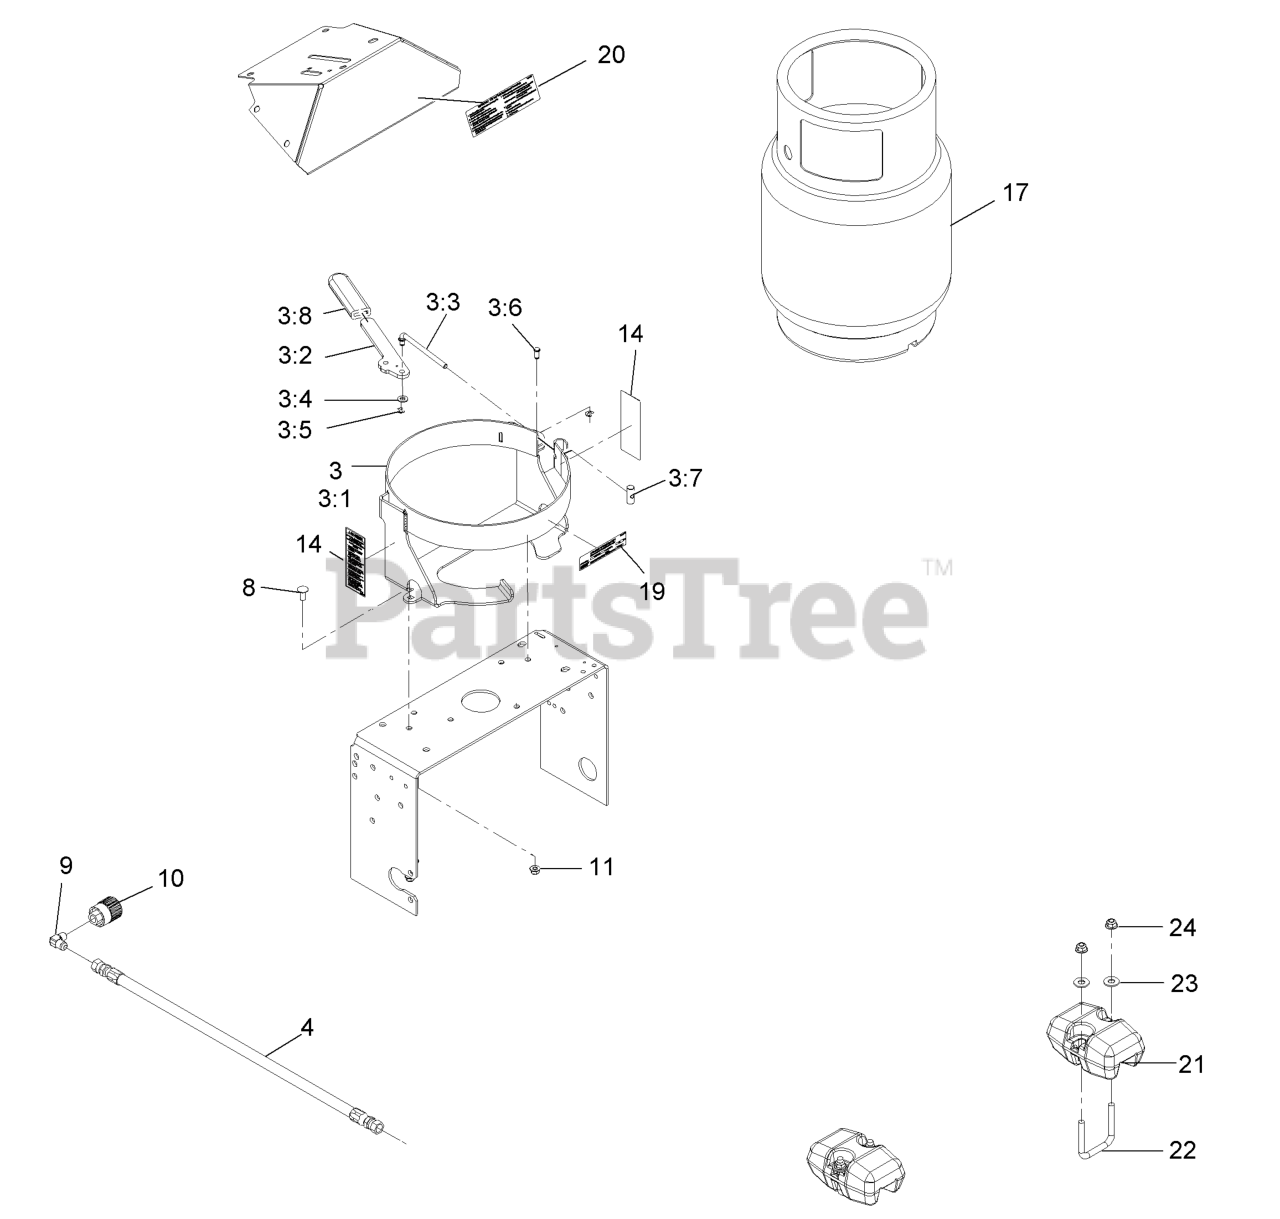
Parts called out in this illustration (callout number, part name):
3	ASM, LP TANK MOUNT
3:1	WELD, TANK MOUNT
3:2	ARM, LEVER
3:3	LINKAGE, LATCH
3:4	WASHER-PLAIN
3:5	E-RING,5/16 HEAVY DUTY
3:6	PIN-CLEVIS
3:7	TRUNNION, LATCH
3:8	GRIP-LEVER
4	ASM, HOSE-LPG
8	BOLT-CARR
9	ELBOW 90DEG,1/4 NPT X3/8
10	CONNECTOR-LPG TANK, LH TH
11	NUT-HF, NI
14	DECAL-LPG WARNING
19	DECAL,LPG TANK SPEC VERTI
20	DECAL-TANK REPLACEMENT
21	WEIGHT-SUPPORT, CASTER
23	WASHER-FLAT
24	NUT-HF, NI
